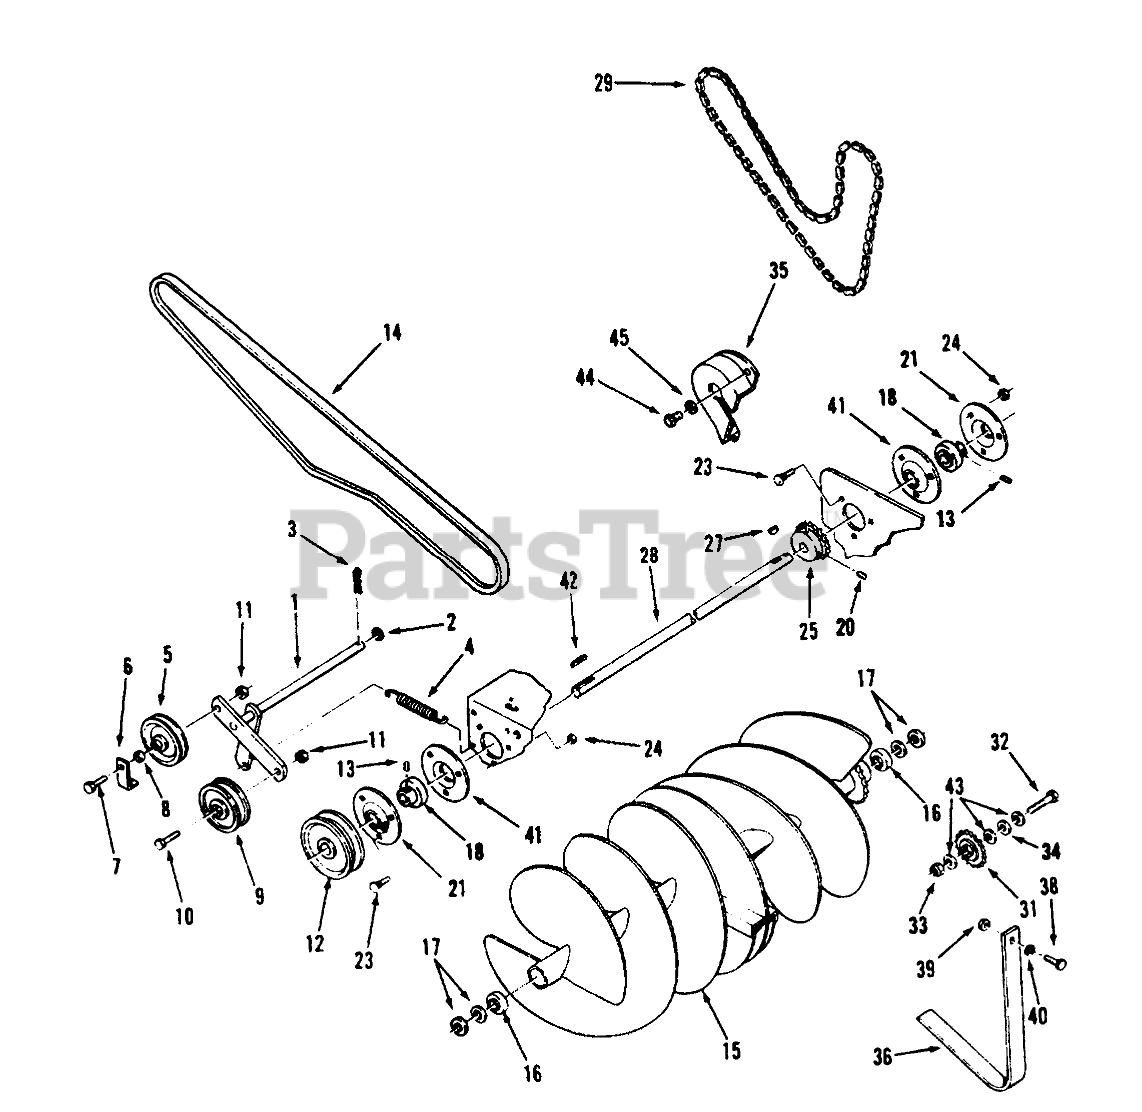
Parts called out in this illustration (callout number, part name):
1	Arm Idler
2	WASHER-FLAT
3	PIN-COTTER
4	SPRING-EXTENSION
5	PULLEY-IDLER
6	Spacer
7	SCREW-HH
8	SPACER
9	Idler Pulley
10	SCREW-HH
11	NUT-LOCK, NI
12	PULLEY
13	SCREW-SQH
14	V-BELT
15	Auger
16	BEARING-BALL
17	WASHER-FLAT
18	BEARING AND COLLAR
20	SCREW-SET, HSH
21	FLANGE-ZERK RELUBE
23	Bolt-Carriage
24	NUT-LOCK, NI
25	SPROCKET-14T H.T.
27	KEY-WOODRUFF
28	Shaft
29	CHAIN
31	Idler Sprocket
32	SCREW-HH
33	NUT-LOCK, NI
34	SPACER
35	GUARD-CHAIN
36	Guard
38	SCREW-HH
39	NUT-KEPS
40	WASHER-FLAT
41	Flange
42	KEY-STRAIGHT
43	WASHER-FLAT
44	Bolt
45	WASHER-FLAT
